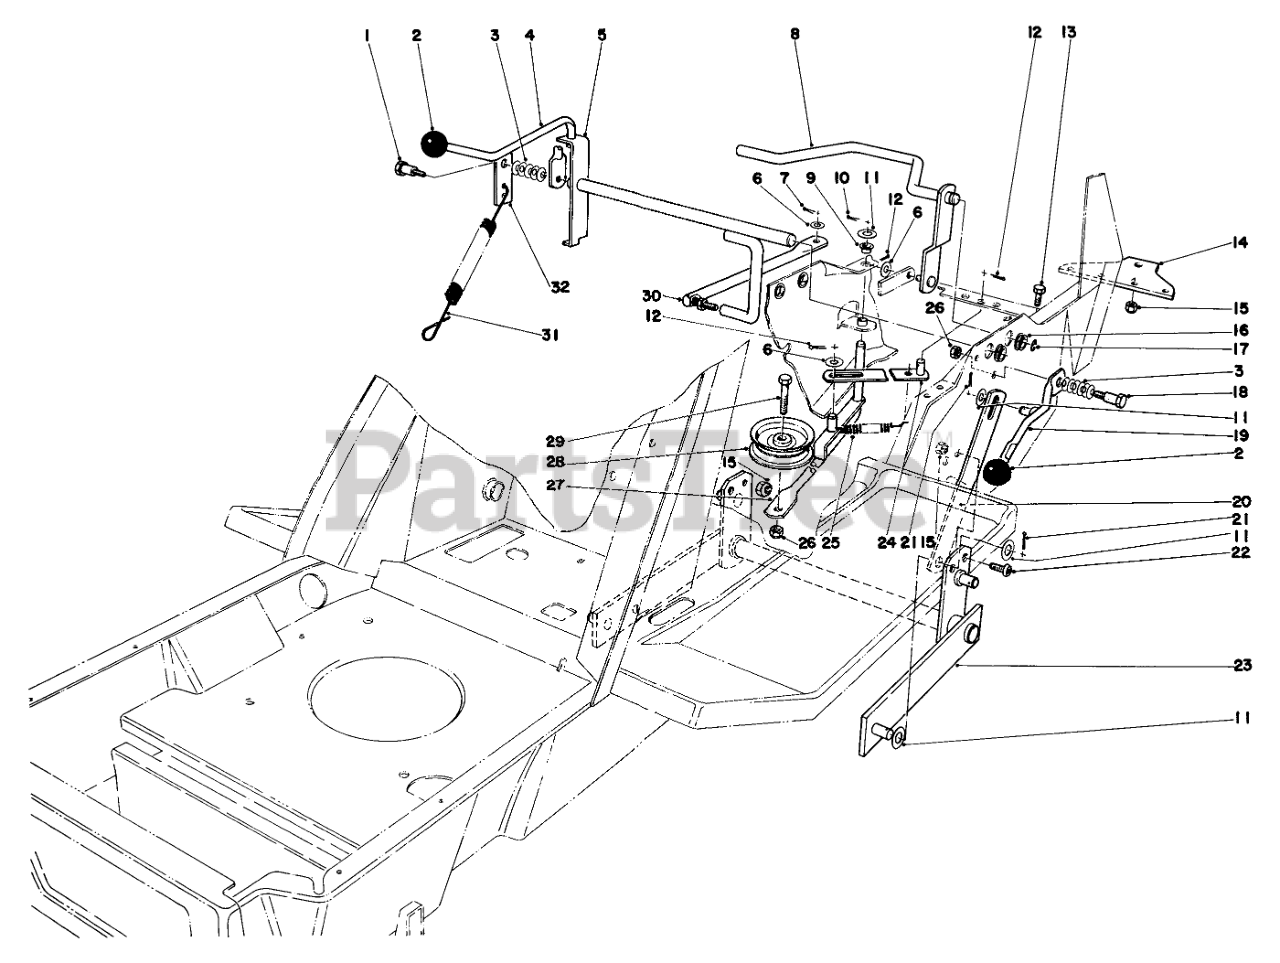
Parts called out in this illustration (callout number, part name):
1	BOLT-SHOULDER
3	WASHER-BELLEVILLE
4	SHIFT LEVER BO
5	Shim Lever
6	WASHER-PLAIN
7	PIN-COTTER
8	CLUTCH ACTUATOR WA B
9	BUSHING-NYLINER
10	PIN-COTTER
11	WASHER-FLAT
12	PIN-COTTER
13	SCREW-HHF
14	HITCH PLATE R
15	NUT-LOCK, CONE
16	Nyliner
17	E-RING
18	SHOULDER BOLT
19	Handle-Height of Cut
20	HOC LINK B
21	PIN-COTTER
22	SCREW-HSBH
23	Pivot Bar
24	SPRING RET WA B
25	DECK TENSION SPRNG O
26	NUT-LOCK, CONE
27	IDLER ARM WA BO
28	IDLER PULLEY
29	SCREW-HH
30	SHIFT ARM BO
31	EXT SPRING O
32	Bracket Counterbalance Spring
